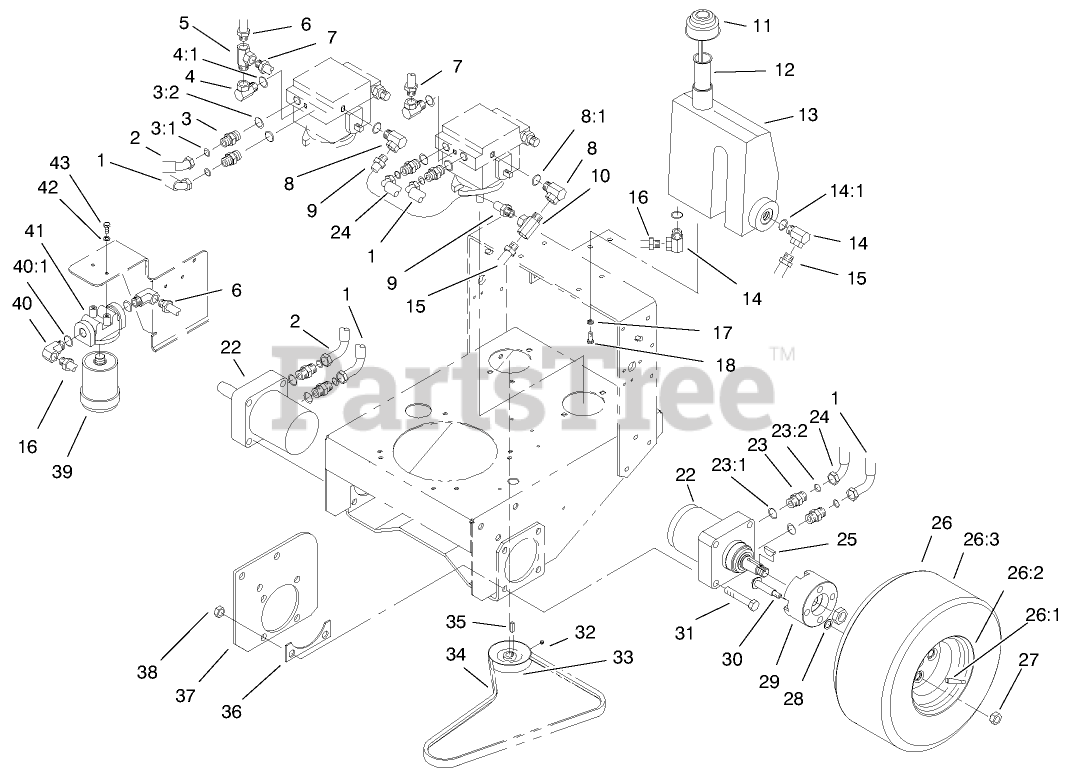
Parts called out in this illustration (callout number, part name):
1	HYDRAULIC HOSE ASM
2	HYDRAULIC HOSE ASM
3	FITTING-STRAIGHT
3:1	O-RING
3:2	O-RING
4	SWIVEL-PIPE, FEMALE
5	FITTING-HYD, TEE
6	HYD HOSE ASM
7	HYD HOSE ASM
8	FITTING-HYD, 90 DEG
8:1	O-RING
9	HYD HOSE ASM
10	FITTING-HYD, TEE
11	OIL CAP ASM
12	SCREEN-FILLER
13	RESERVOIR-OIL
14	FITTING-HYD, 90 DEG
15	HYDRAULIC HOSE ASM
16	HYD HOSE ASM
17	WASHER-LOCK
18	SCREW-HH
22	WHEEL MOTOR ASM
23	FITTING-STRAIGHT
23:1	O-RING
23:2	O-RING
24	HYDRAULIC HOSE ASM
25	KEY-WOODRUFF
26	ASM-Wheel & Tire
26:1	STEM-VALVE
26:2	WHEEL
27	NUT-LUG
28	PUSHNUT
29	HUB-WHEEL
30	SCREW-HH
31	SCREW-HH
32	SCREW-SET
33	PULLEY-PUMP
34	BELT-V
35	KEY-PUMP
36	SPACER-FRAME
37	PLATE-FRAME
38	NUT-LOCK, NI
39	CARTRIDGE-FILTER, OIL
40	FITTING-HYD, 90 DEG
40:1	O-RING
41	HEAD-FILTER
42	WASHER-LOCK
43	SCREW-HH
